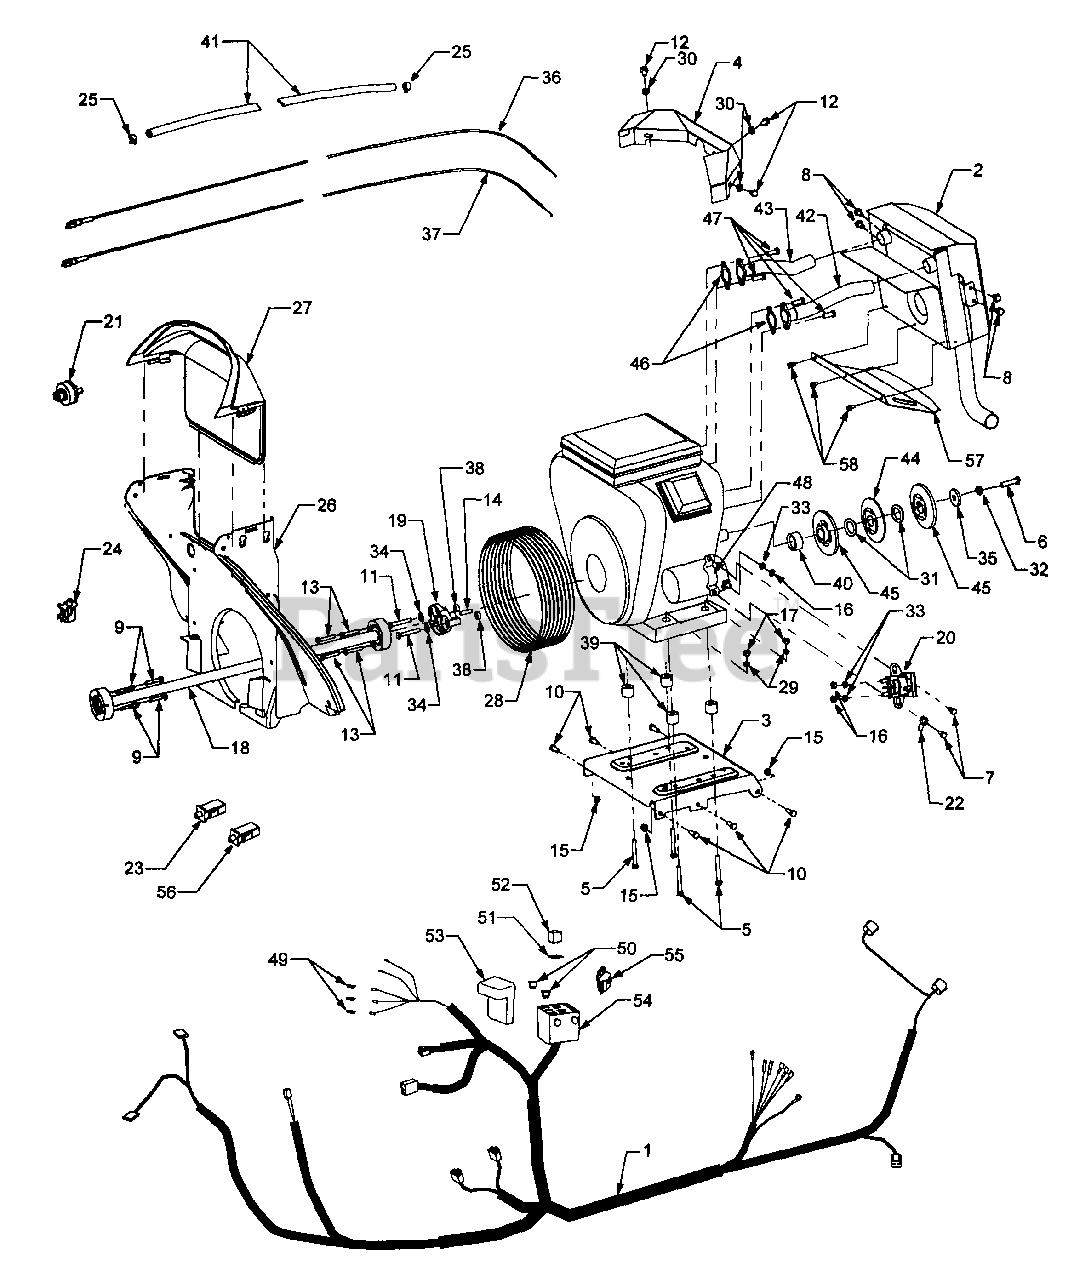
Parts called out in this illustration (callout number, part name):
1	Harness, Wire
1	Cable Tie
1	Tie, Pushmount
1	Clip, Cable
2	Muffler Assembly
3	Plate, Engine Mounting
4	Shield, Muffler Heat
5	Screw, Hex Cap, 5/16-18 x 2.5 GR5
6	Screw, Hex Cap, 3/8-24 x 1.5 GR5
7	Screw, Hex Wash. Hd. Tapp 1/4-20 x .5
8	Screw, Hex Wash. Hd. Tapp 5/16-18 x .5
9	Screw, Hex Wash. Hd. Tapp 1/4-20 x 1.5
9	Screw, Hex Cap Lock 1/4-20 x 1.62 GR5
10	Screw, Hex Cap, 5/16-18 x .875 GR5
11	Screw, Hex Cap, 5/16-18 x 2.0 GR5
12	Screw, Hex Cap, M6 - 1.0 x 10MM
13	Screw, Hex Cap, Lock 1/4-20 x 1.62 GR5
14	Pin, Locating
15	Nut, Hex Insert Lock, 5/16-18
16	Nut, Hex, 1/4-20
17	Nut, Hex , 5/16-18
18	Shaft, Drive, 28.75 Long
19	Adapter, Drive Shaft
21	Switch, Ignition
22	Quick Connect Lug
23	Switch, Plunger
24	Switch, Snap Mount
25	Clamp, Hose
26	Baffle, Lower Air
27	Baffle, Upper Air
28	Boot, Intake
29	Washer, Lock, 5/16
30	Washer, Flat, .281 x .50 x .06
31	Washer, Flat Shim (Hdn)
32	Washer, Lock, 3/8
33	Washer, Lock, 1/4
34	Washer, Flat, .344 x .75 x .12
35	Washer, Flat, .417 x 1.5 x .225
36	Cable, Throttle Control
37	Cable, Choke Control
38	Spacer, .38 x .62 x .275
39	Spacer, Engine Mtg. 1.0 x .335 x .875
40	Spacer, Crankshaft
41	Hose, Fuel Line
42	Pipe, Exhaust RH
43	Pipe, Exhaust LH
44	Pulley, Center
45	Pulley, Half
46	Gasket, Exhaust
47	Screw, Exhaust Pipe
48	Bracket, Solenoid Mtg.
48	Clamp, Band
49	Bulb, Indicator
50	Fuse, 25 Amp
51	Gasket, Silicone
52	Relay, PTO
53	Cover, Fuse Box
54	Box, Fuse
55	Sensor, Voltage
56	Switch, Plunger
57	Shield, Lower Exhaust
58	Screw, Hex Wash. Hd. Tapp, #12-24 x .38
